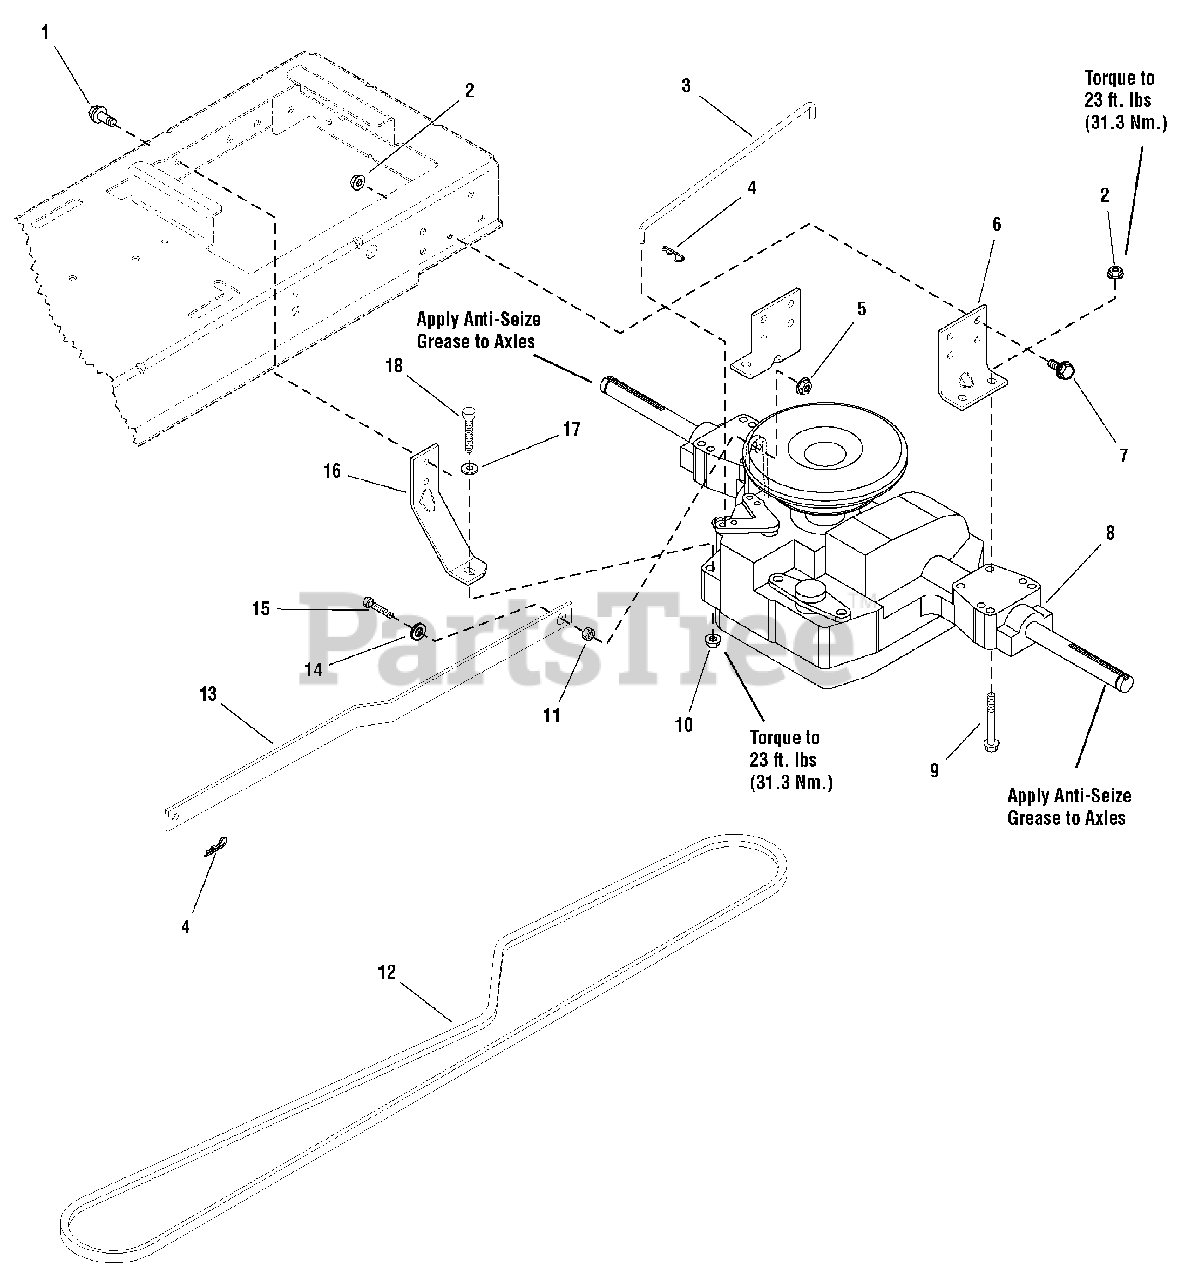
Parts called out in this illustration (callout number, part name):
1	CAPSCREW, Hex Head, Taptite, 5/16-18 x 3/4
2	NUT, Hex, Flange Whizlock, 5/16-18
3	ROD, Bypass, 11.44 LG Yellow
4	PIN, Quick
5	NUT, Hex Flange, 5/16-18 ESNA
6	SUPPORT, Transmission
7	CAPSCREW, Hex Head, Flange Whiz Lock, 5/16-18 x 3/4
8	* TRANSMISSION, Tuff Torq K46BL
9	SCREW, Hex Head Flange Lock, 5/16-18 x 2-1/2
10	NUT, Hex Flange, 5/16-18 ESNA
12	V-BELT, Drive Belt, Aramid/Kevlar
13	ARM, Control 7GA
14	WASHER, Flat, 5/16
15	CAPSCREW, Hex Head, 5/16-18 x 1
16	STRAP, Torque 7 GA
17	WASHER, Plain, 5/16
18	CAPSCREW, Hex Head, 5/16-18 x 1-3/4
